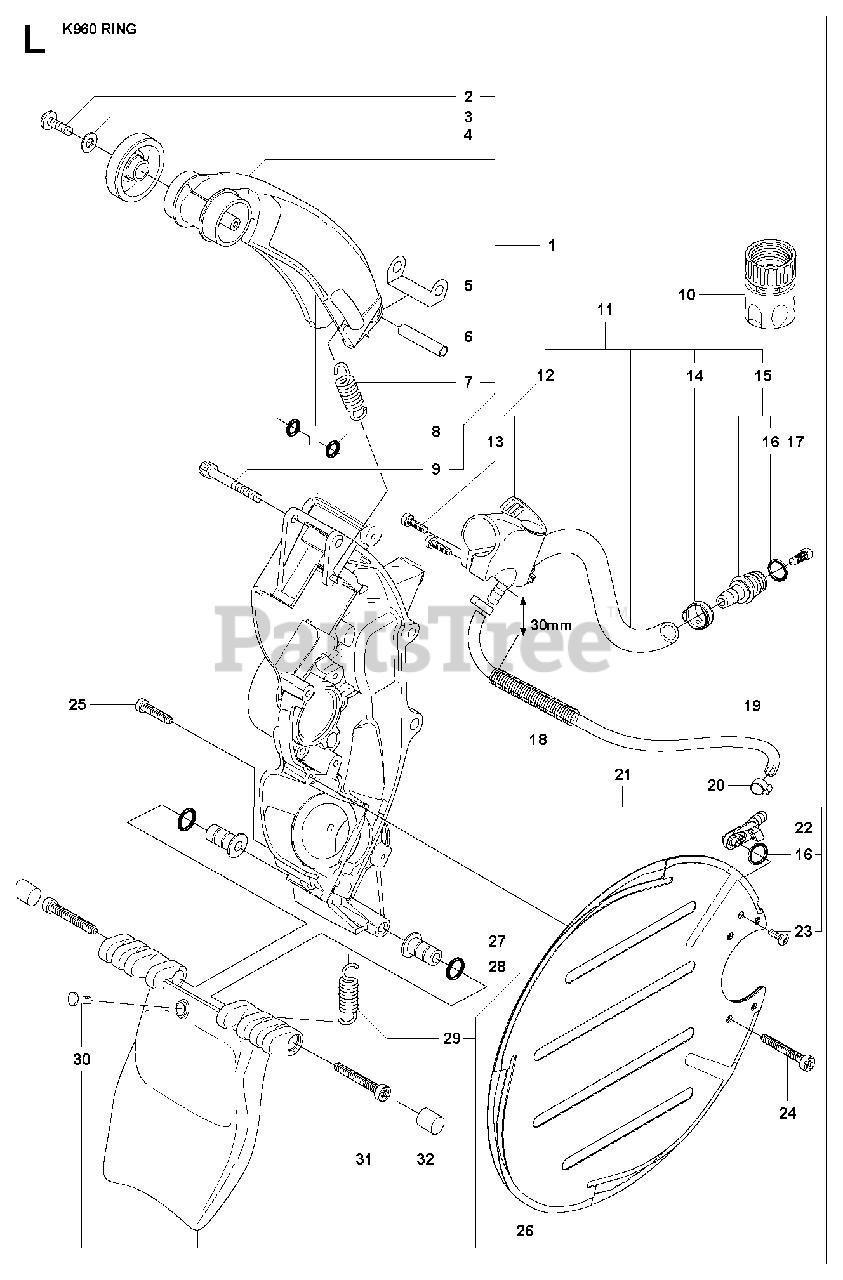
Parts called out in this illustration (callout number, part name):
1	BLADE GUARDIncl. 2 - 9
6	SPACING TUBE
9	SCREW ITXSCM
11	HOSE ASSYIncl. 12, 14 - 15
12	VALVE ASSYIncl 13
13	SCREW ITXSCT
14	HOSE CLAMP
15	NIPPLEIncl. 16, 17
16	O-RING
18	PROTECTIVE SPRING
19	HOSE210 mm
20	HOSE CLAMP
23	SCREW CRPANT
25	SCREW ITXSCM
26	SPRAY GUARD ASSYIncl. 27 - 32
31	SCREW ITXSCM
